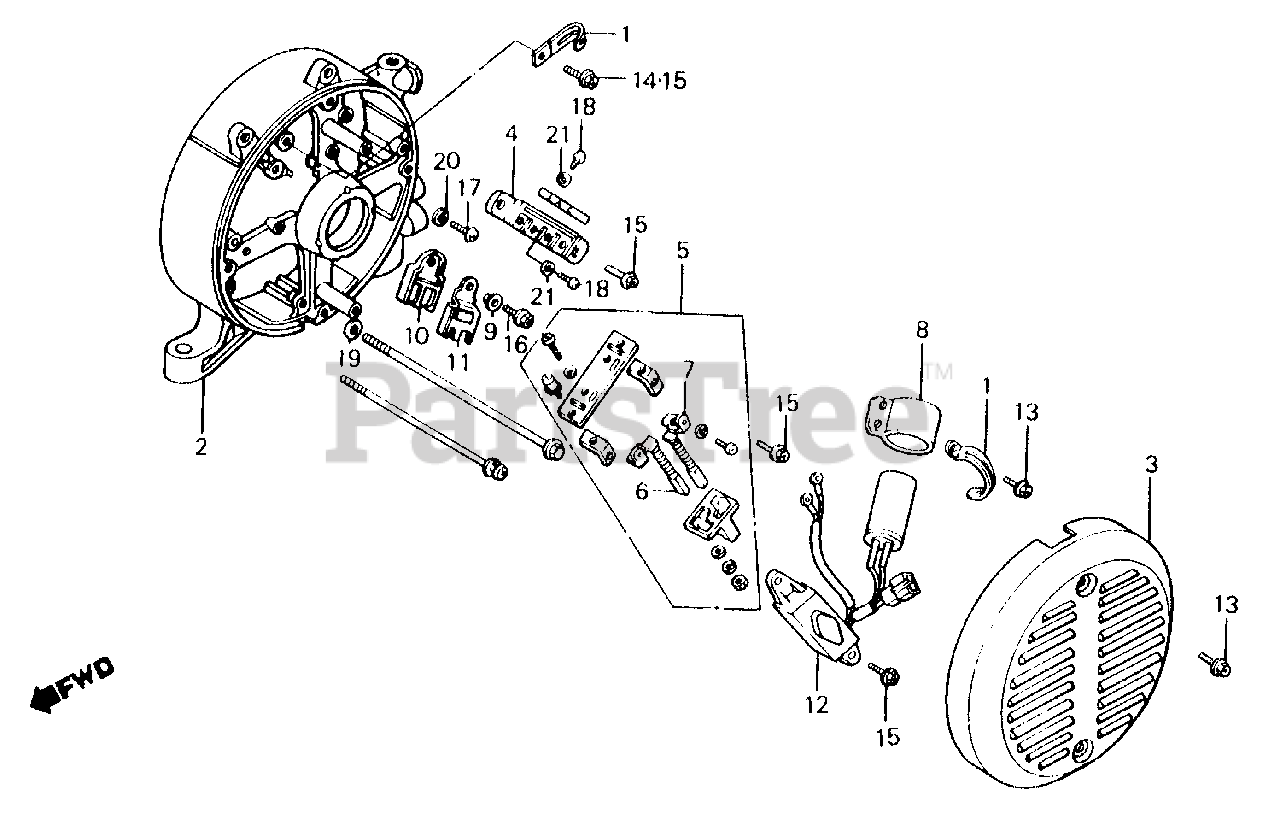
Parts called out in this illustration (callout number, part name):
1	CLAMP B, WIRE
2	HOUSING, RR. *R8* (BRIGHT RED) (NOT AVAILABLE)
3	COVER, ALTERNATOR END *R8* (BRIGHT RED) (NOT AVAILABLE)
4	TERMINAL, A.C. OUT
5	HOLDER ASSY., BRUSH
8	HOLDER, CONDENSER
12	REGULATOR ASSY., AUTOMATIC VOLTAGE
13	SCREW, TAPPING (5X12)
14	SCREW, TAPPING (5X14)
15	SCREW, TAPPING (5X14)
16	SCREW, TAPPING (5X16)
17	SCREW, PAN (5X12)
18	SCREW, PAN (6X8)
19	WASHER, PLAIN (6MM)
20	WASHER, SPRING (5MM)
21	WASHER, SPRING (6MM)
NI	BOLT, HEX. (6X160)
